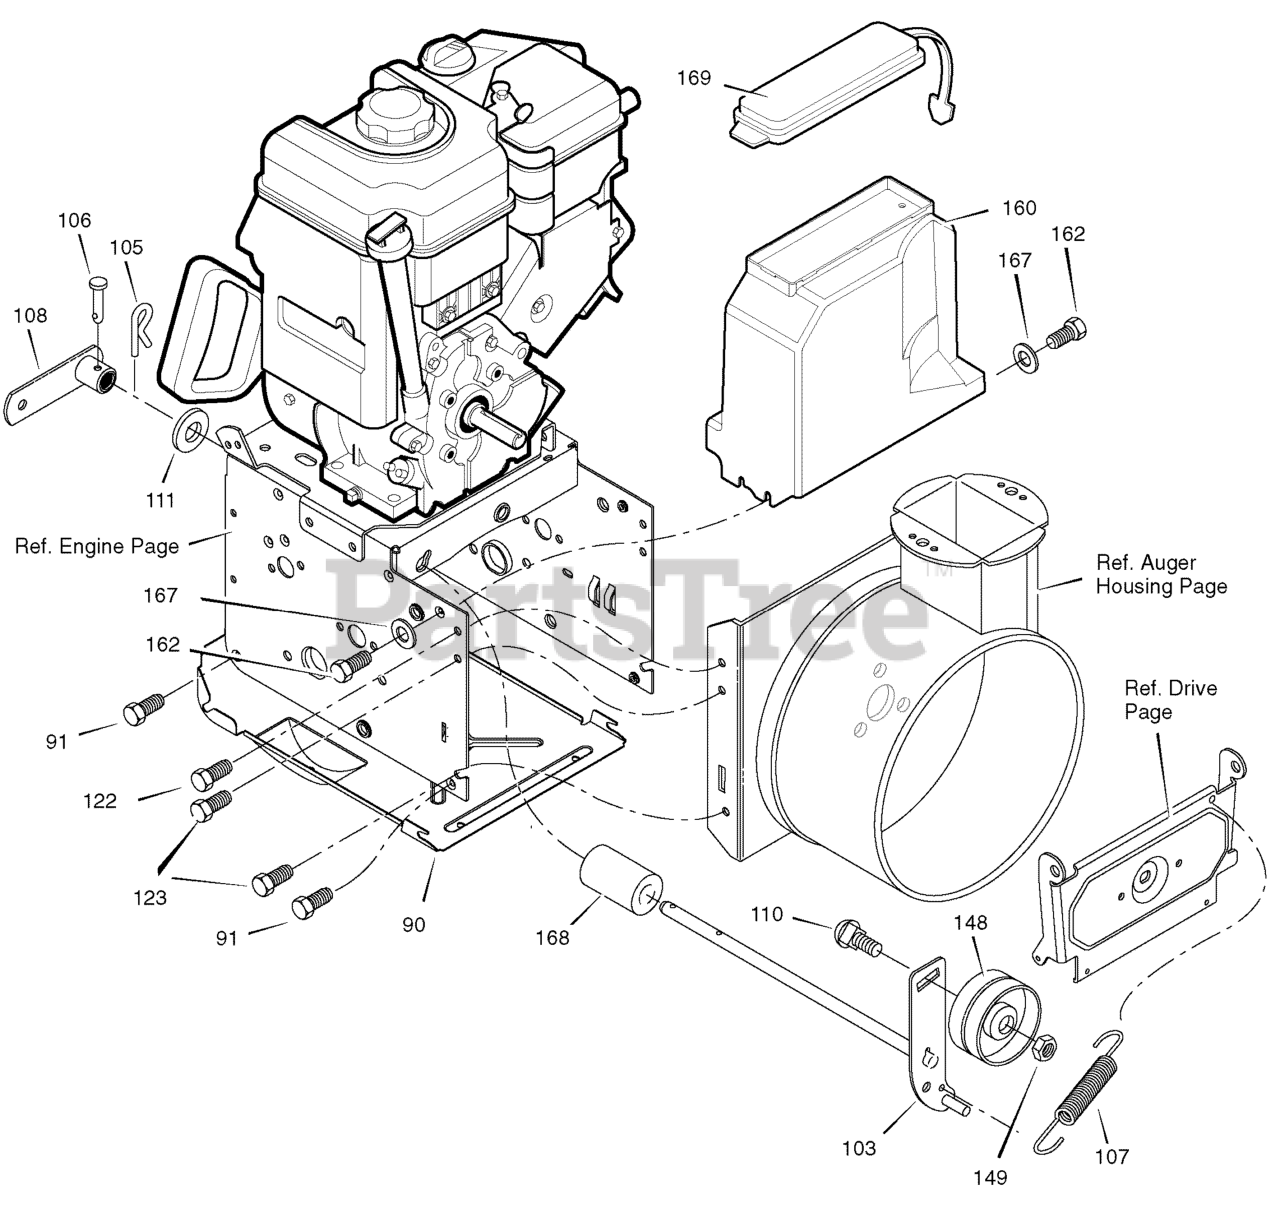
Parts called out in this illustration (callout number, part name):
90	COVER, BOTTOM
91	SCREW, 1/4-20X .63
103	IDLER ASSEMBLY, AUGER
105	PIN, HAIR .38DIAX1.64LG
106	PIN, CLEVIS 3/16" DIA
107	SPRING, TENSION
108	ASSY., SPRING ATTACH
110	BOLT, 3/8-16X1.25 CARR.
111	WASHER, FLAT
122	SCREW, TAP 5/16-18 X .50
123	SCREW, TAP 5/16-18 X .75
148	PULLEY, IDLER
149	NUT, JAM 3/8-16
160	COVER, BELT
162	SCREW, TAP
167	WASHER, FLAT
168	SPACER, AUGER BRACKET
169	LID, TOOL BOX
